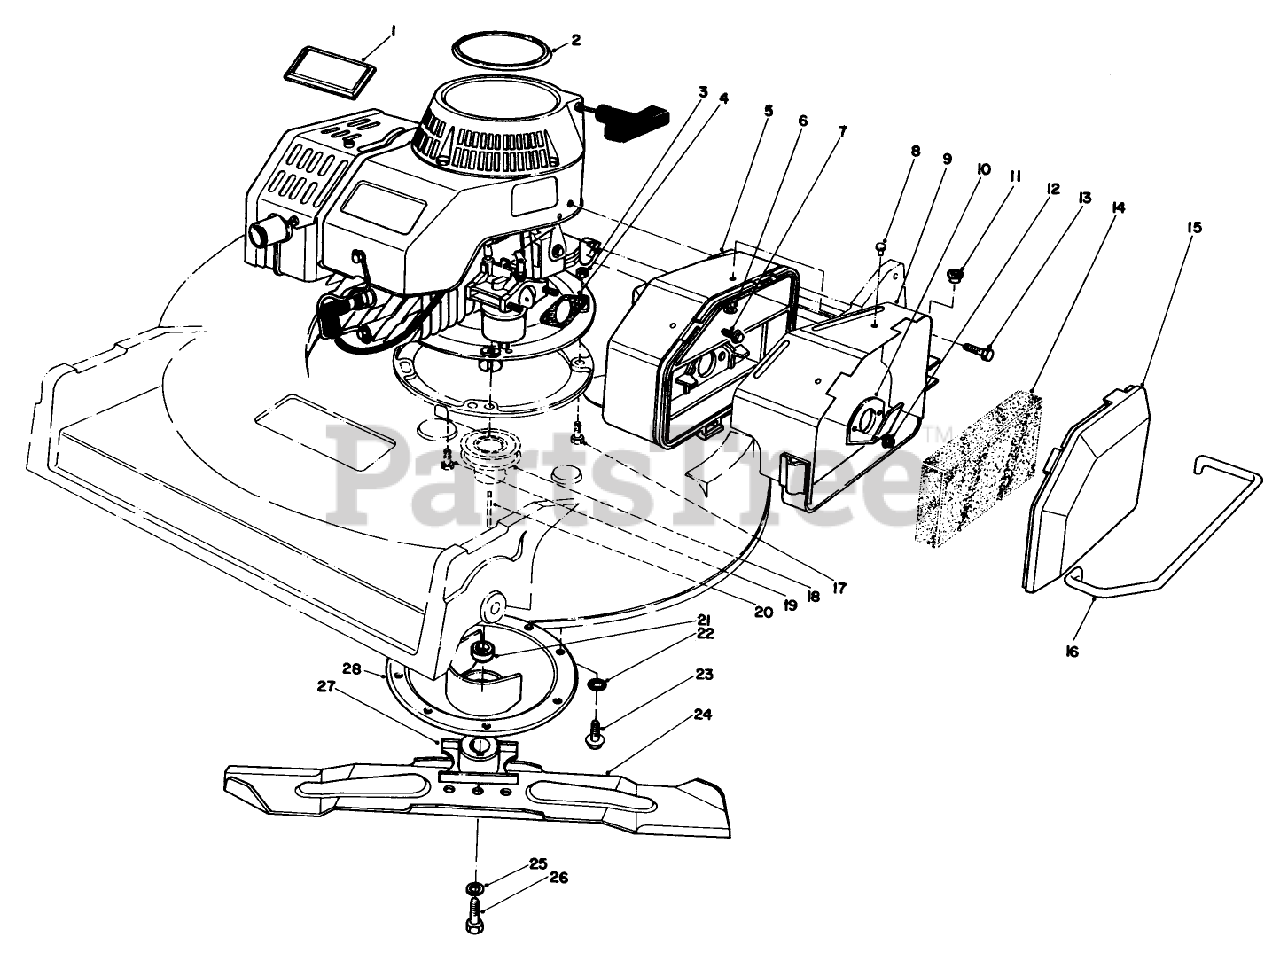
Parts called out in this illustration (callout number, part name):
3	NUT-JAM
4	GASKET-AIR CLEANER
5	AIR CLEANER ASM
6	WASHER-FLAT
8	NUT-HEX
10	SPIT BACK DEFLECTOR
13	SCREW-HHF
14	FILTER
16	AIR CLEANER GUARD*
17	SCREW-HH
18	PULLEY-DRIVER
19	SCREW-HH
20	KEY-SQUARE
21	SPACER-BLADE RETAINER
22	WASHER-LOCK, INTERNAL
23	SCREW-THD ROLL, HWH
25	WASHER-LOCK
26	SCREW-BLADE
